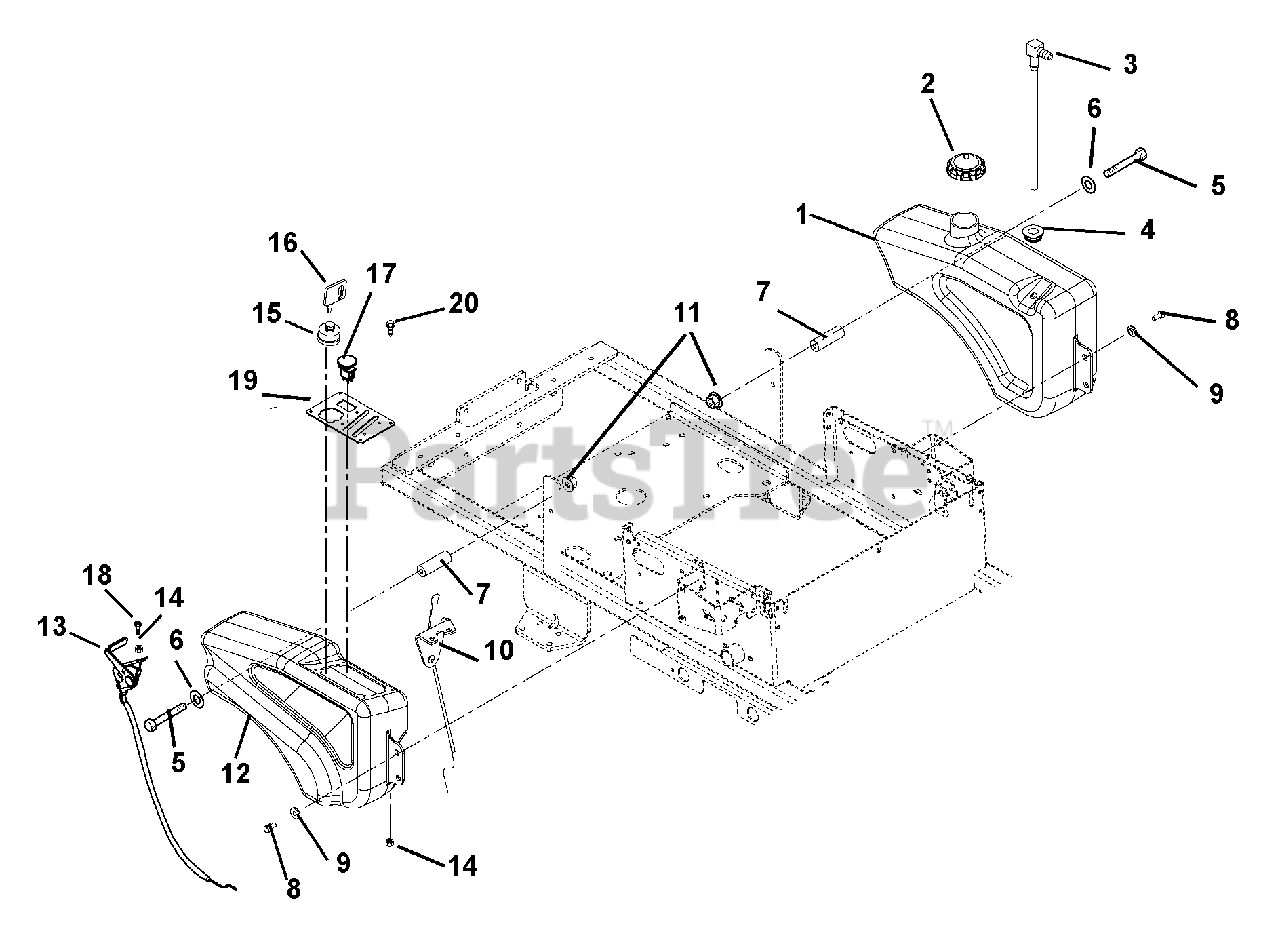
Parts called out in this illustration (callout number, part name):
1	Gas Tank HVZ
2	Fuel Cap
3	Fitting, Tank
4	Bushing, Flange .375 x 1.062 x .625
5	Bolt, Hex .31-18 x 3.50 Grade 5
6	Washer, Flat-Steel .38 x .875 x .083
7	Spacer, HVZ Tank Mount
8	Bolt, Hex .31-18 x .75 Grade 5
9	Shoulder Spacer
10	Cable, Choke Cable
11	Nut, .31-18 Nyloc Flange
12	Fender HVZ
13	Cable, Throttle
14	Nut-Locking-Nylon 10-24 with Insert
15	Key Switch
16	Key, w/cap
17	Switch, Clutch
18	Screw-Machine 10-24 x .75 Hex Washer Head
19	Control Panel
20	Rivet, Plastic .195 Diameter
